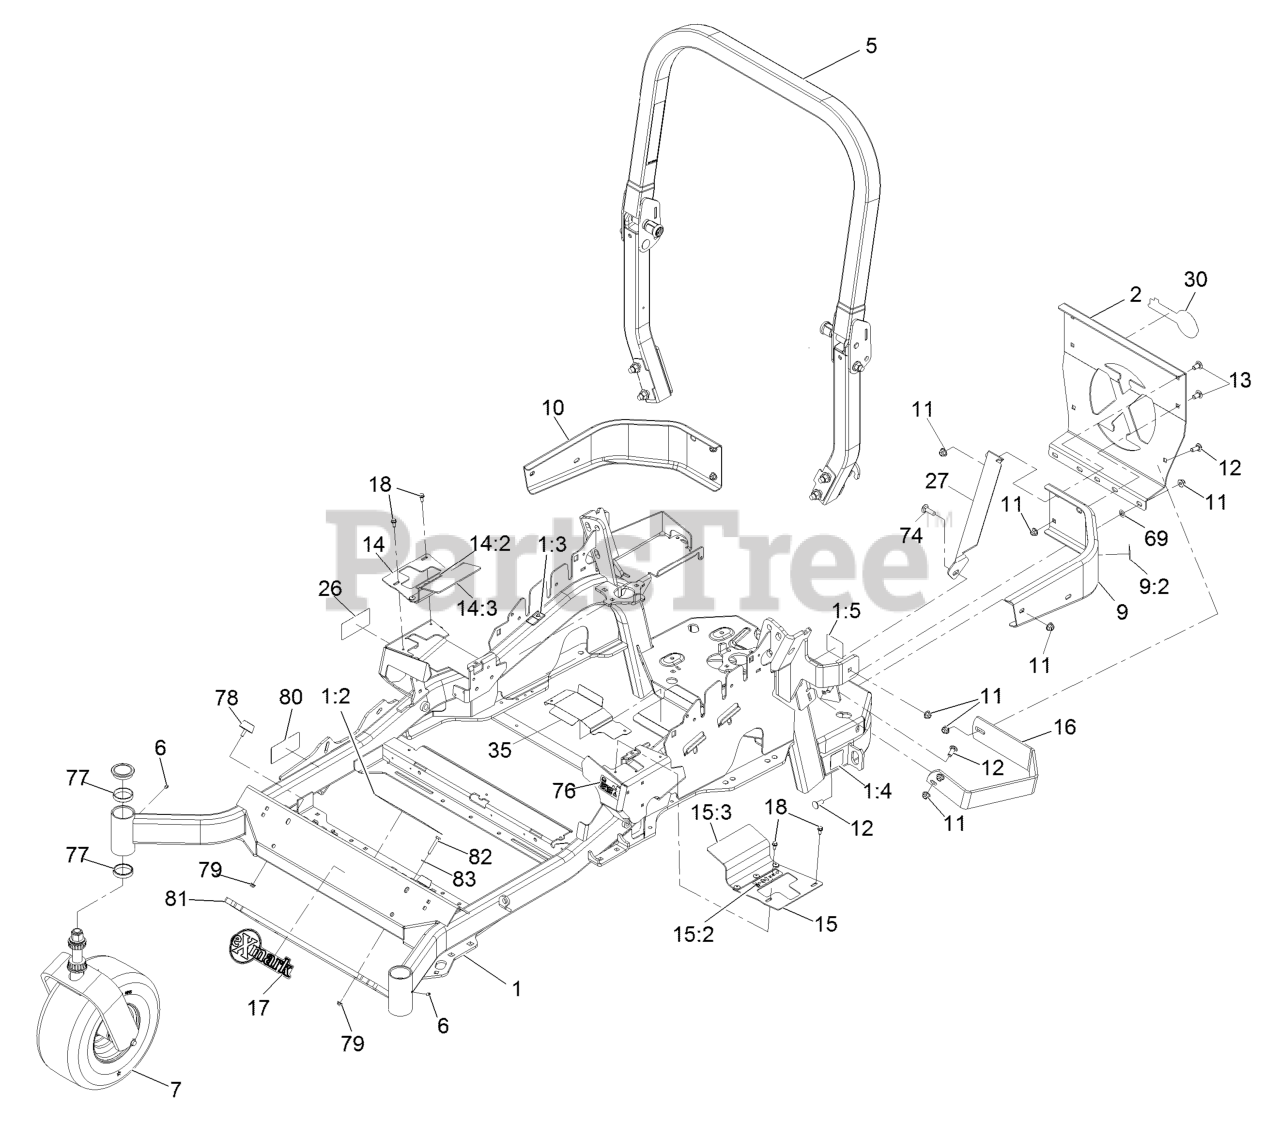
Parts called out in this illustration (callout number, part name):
1:2	DECAL-DANGER
1:3	DECAL-WARNING
1:4	DECAL-HAZARD, PINCHED FINGER
1:5	DECAL-SPARK ARRESTER
2	PLATE,REAR GUARD
5	ROPS ASM
7	Front Caster And Fork ASM
9	LH BUMPER ASM
9:2	DECAL-WARNING
10	BUMPER-RH
11	NUT-HF, NI
12	SCREW-CARR
13	SCREW-CARR
14	RH MOTION CONTROL COVER A
14:2	DECAL-CONTROL, MOTION
14:3	FLAP-RUBBER
15	LH MOTION CONTROL COVER A
15:2	DECAL-CONTROL, MOTION
15:3	FLAP-RUBBER
16	GUARD-MUFFLER
17	DECAL-EXMARK LOGO
18	SCREW-HWH
26	DECAL-E-SERIES
30	DECAL-EXMARK LOGO
35	GUARD-BELT
69	NUT-PUSH
74	BOLT-CARR
76	DECAL-FUEL FILL, CE
77	CUP-BEARING
80	Decal-Patent Ttco.Com
81	WEIGHT-TOE BOARD
82	SCREW-HH
83	WASHER-FLAT
